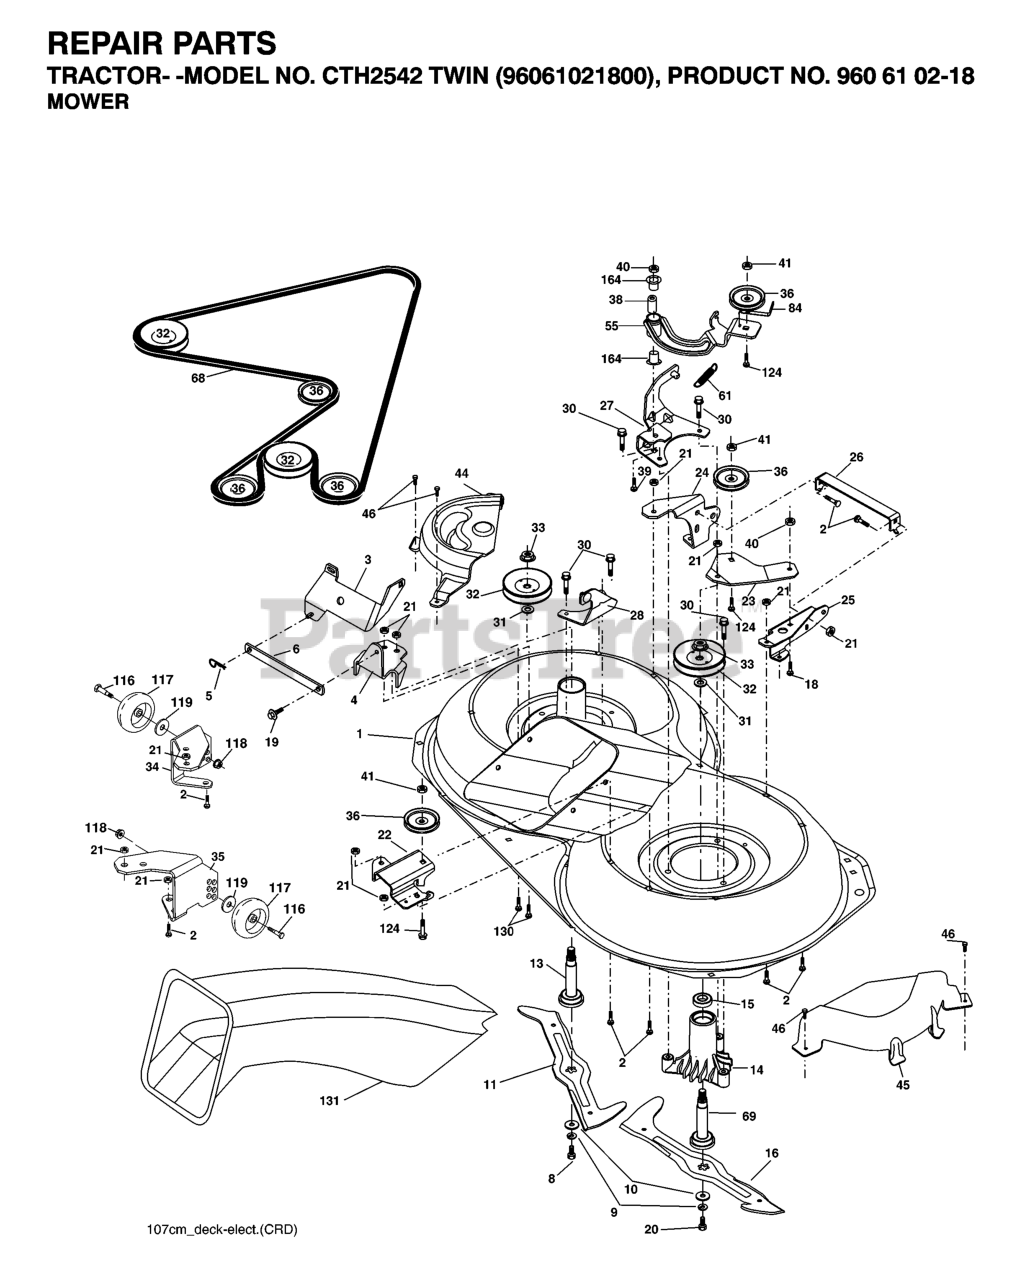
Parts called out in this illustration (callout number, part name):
1	Housing Asm. Mower 107 CRD
2	RP BOLT 5/16-18 X3/4 ZN/YEL GR
5	RETAINER-SPRNG RB
6	BAR.SWAY.92.CRD
8	BOLT.3/8-24X1.25 GR8
9	LOCKWASHER
10	WASHER.BLADE
11	BLADE.3N1.LH.CRD
13	SHAFT ASM VENT
14	HOUSING.MANDREL.VENTED (MACHD)
16	BLADE.3N1.RH.CRD
19	BOLT SHD 5/16-18
20	BOLT.3/8-24X1.25GR8. LHTHRD
21	LOCKNUT
22	BRACKET.IDLER.RR.107.CRD
25	BRACKET RF
26	SUPPORT
28	BRACKET
30	SCREW, WASHER HEAD
31	WASHER.SPACER.MANDREL
32	PULLEY.MANDREL.4.80 PD.2006
33	NUT.FLANGE.LOCK.TOP
34	BRACKET
35	BRACKET
36	PULLEY.IDLER.4.25
41	NUT LOCK FLG 3/8-16 UNC
45	COVER.MANDREL.RH.CRD
46	SCREW.1/4-20X5/8
55	ARM.IDLER.107.CRD
61	SPRING
68	HEX-BELT 107 MOWER
69	SHAFT.ASM.W/LWR.BRG.RH.THREAD
84	KEEPER, BELT IDLER
116	BOLT.SHOULDER.3/8-16X3-5/8.
117	RP WHEEL. GUAGE RALLY
118	LOCKNUT
119	WASHER
124	BOLT.3/8-16X1.50
130	BOLT.CARR.SQNK.5/16-18UNC.X3/4
131	CHUTE BAGGER
164	BRNG T
